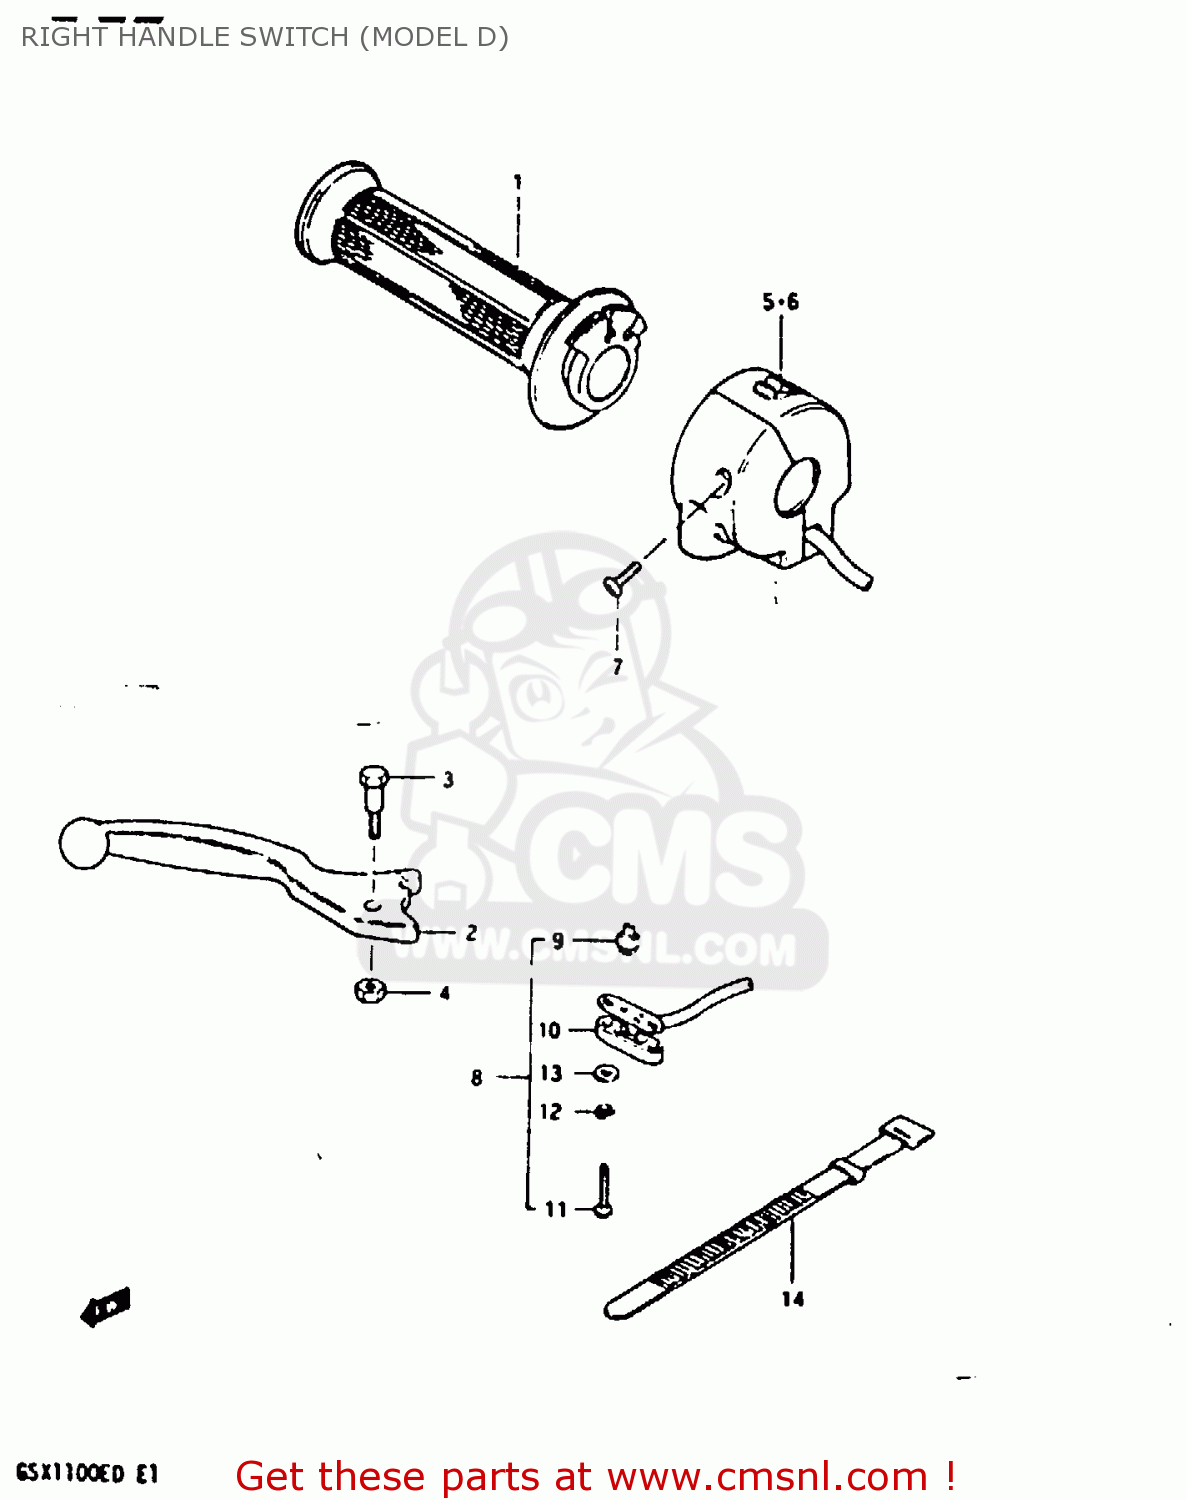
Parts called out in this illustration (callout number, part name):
1	GRIP,THROTTLE
2	LEVER,BRAKE
3	BOLT
4	NUT 6MM
5	SWITCH ASSY,HANDLE,R
6	SWITCH ASSY,HANDLE,R
7	SCREW
8	SWITCH ASSEMBLY
9	CONTACT,SWITCH
10	COVER,FR BK TERMINAL BASE
11	SCREW
12	LOCK WASHER
13	WASHER
14	CLAMP(L:120)
